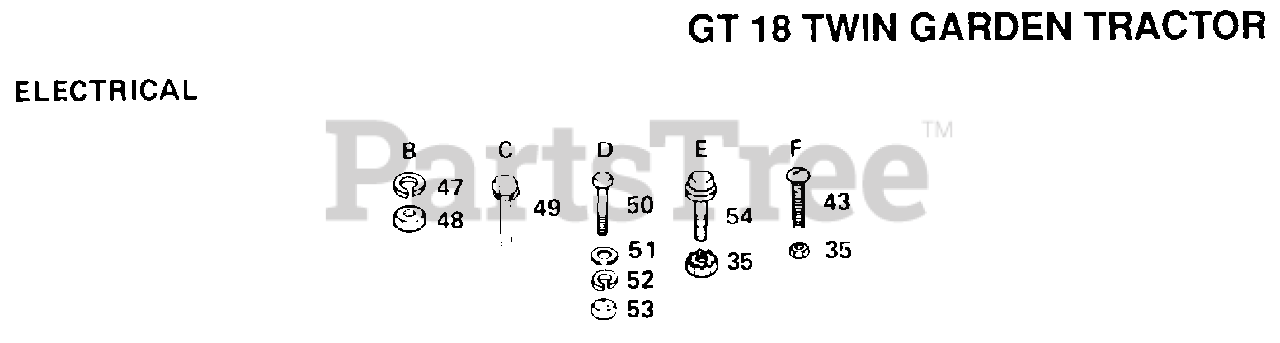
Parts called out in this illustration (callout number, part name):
35	"NUT,KEPS"
48	NUT
49	SCREW ST
50	BOLT LT
51	WASHER
52	LOCKWASHER
54	SCREW
